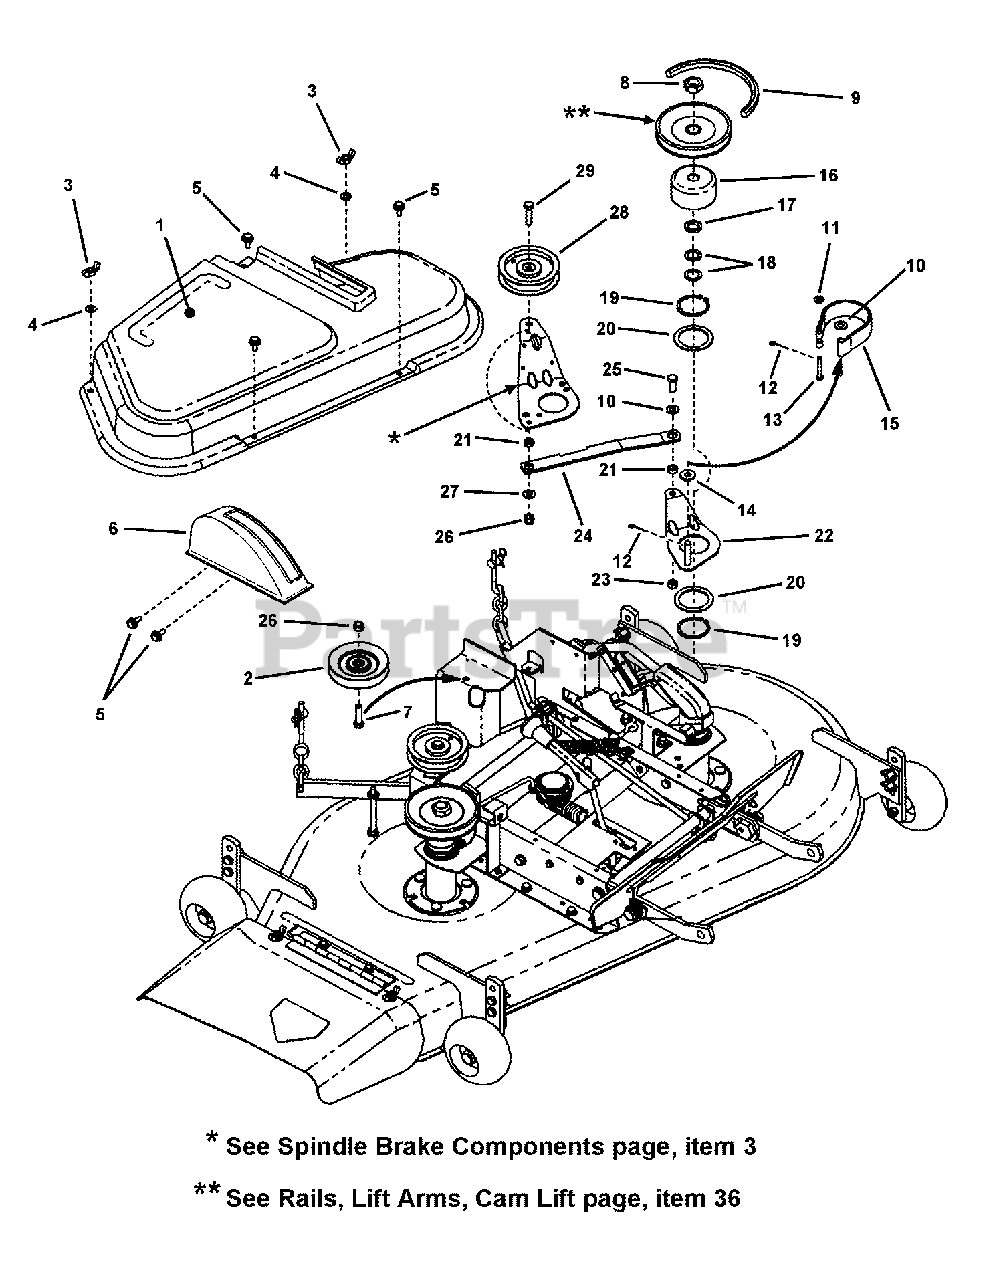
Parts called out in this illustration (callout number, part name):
1	BELT COVER, 42" RER
2	IDLER PULLEY, Seam Welded
3	WING NUT, 5/16-18
4	WASHER, 5/16" Flat
5	SCREW, 1/4-20 x 5/8" Self-Tap w/Loose Captured Washer
6	COVER, Quadrant
7	SCREW, 3/8-16 x 1-1/2" Hex Head Cap, GR 5
8	NUT, 3/4-16 Hex Jam, GR 8
9	BELT, 5L Section, 47.64"
10	WASHER, 3/8" SAE Flat
11	WASHER, 1/4" Flat
12	PIN, 3/32 x 3/4" Cotter
13	PIN, 1/4 x 1-5/8 Clevis
14	SPACER, .39 x 1.01 x .31 Nylon
15	BRAKE BAND (Formed)
16	DRUM, Brake Spindle
18	WASHER, .77 x 1.13 x .06 Flat
19	RING, 2" External Retaining
20	WASHER, Nylon
21	SPACER, .380 x .622/.625 x .25
22	WELDMENT, Brake Arm
23	NUT, 3/8-24 Hex Center Lock
25	SCREW, 3/8-24 x 1" Hex Head Cap, GR 5
26	NUT, 3/8-16 Hex Nyloc
27	WASHER, 3/8" SAE Flat
28	IDLER, 4-1/8" Flat
29	SCREW, 3/8-16 x 1-1/2" Hex Head Cap, GR5
